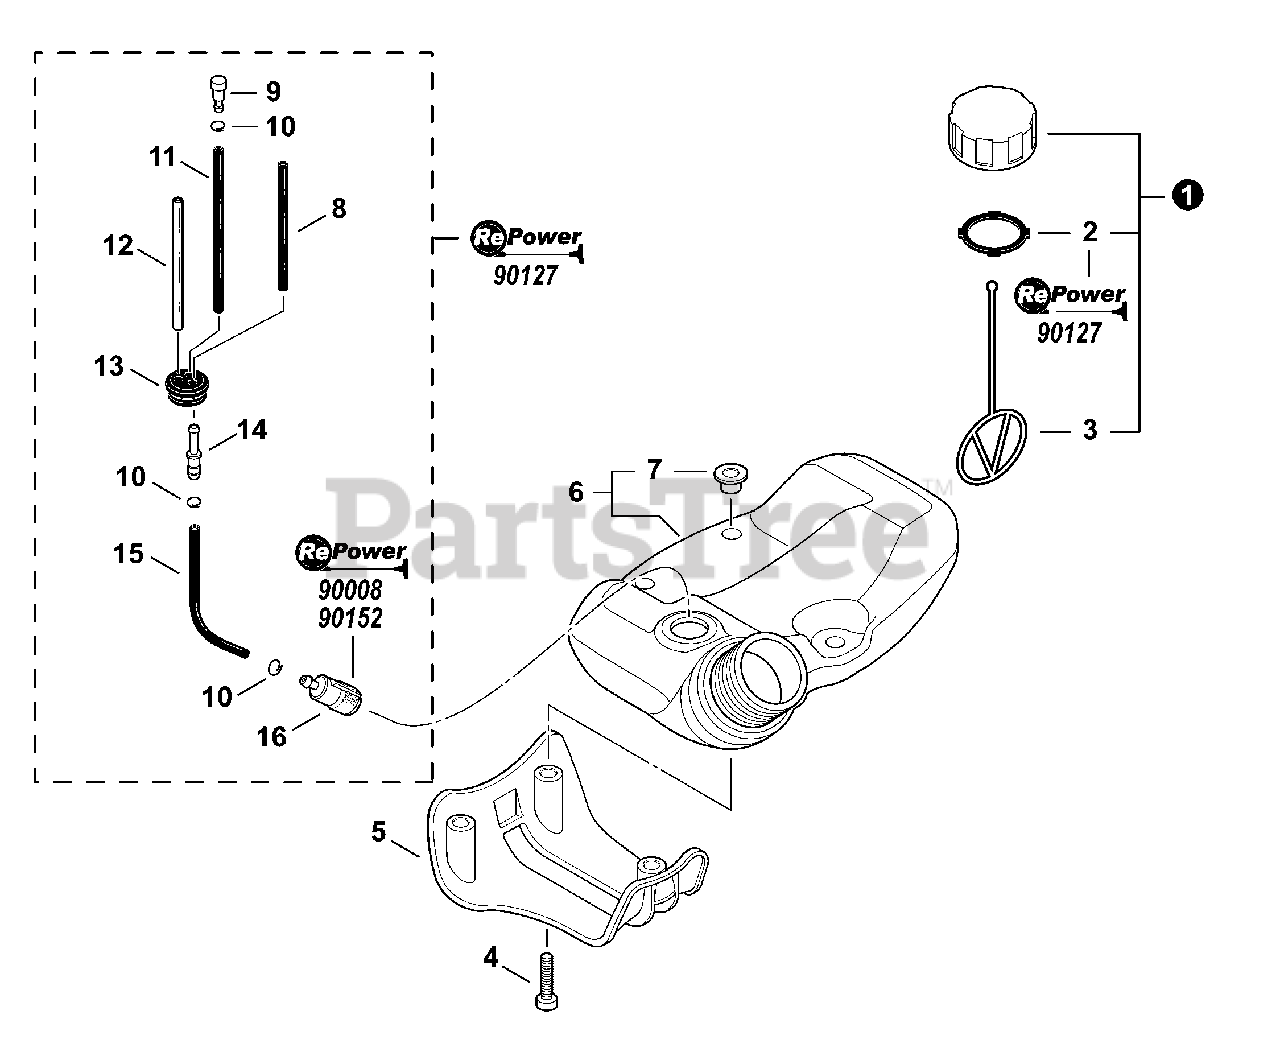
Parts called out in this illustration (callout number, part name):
1	CAP ASSY, FUEL
2	GASKET, FUEL CAP
3	CONNECTOR, CAP L= 123
4	BOLT, TORX 5×25
5	GUARD, FUEL TANK
6	TANK ASSY, FUEL
7	COLLAR 5
8	PIPE, FUEL 3×5×74 BLACK
9	VENT ASSY
10	CLIP Ø6
11	PIPE, FUEL 3×5×90 BLACK
12	PIPE, FUEL 3×6×80 CLEAR
13	GROMMET, FUEL Ø5
14	CONNECTOR, PIPE Ø5ר3.5
15	PIPE, FUEL 3×5×130 BLACK
16	FILTER, FUEL
